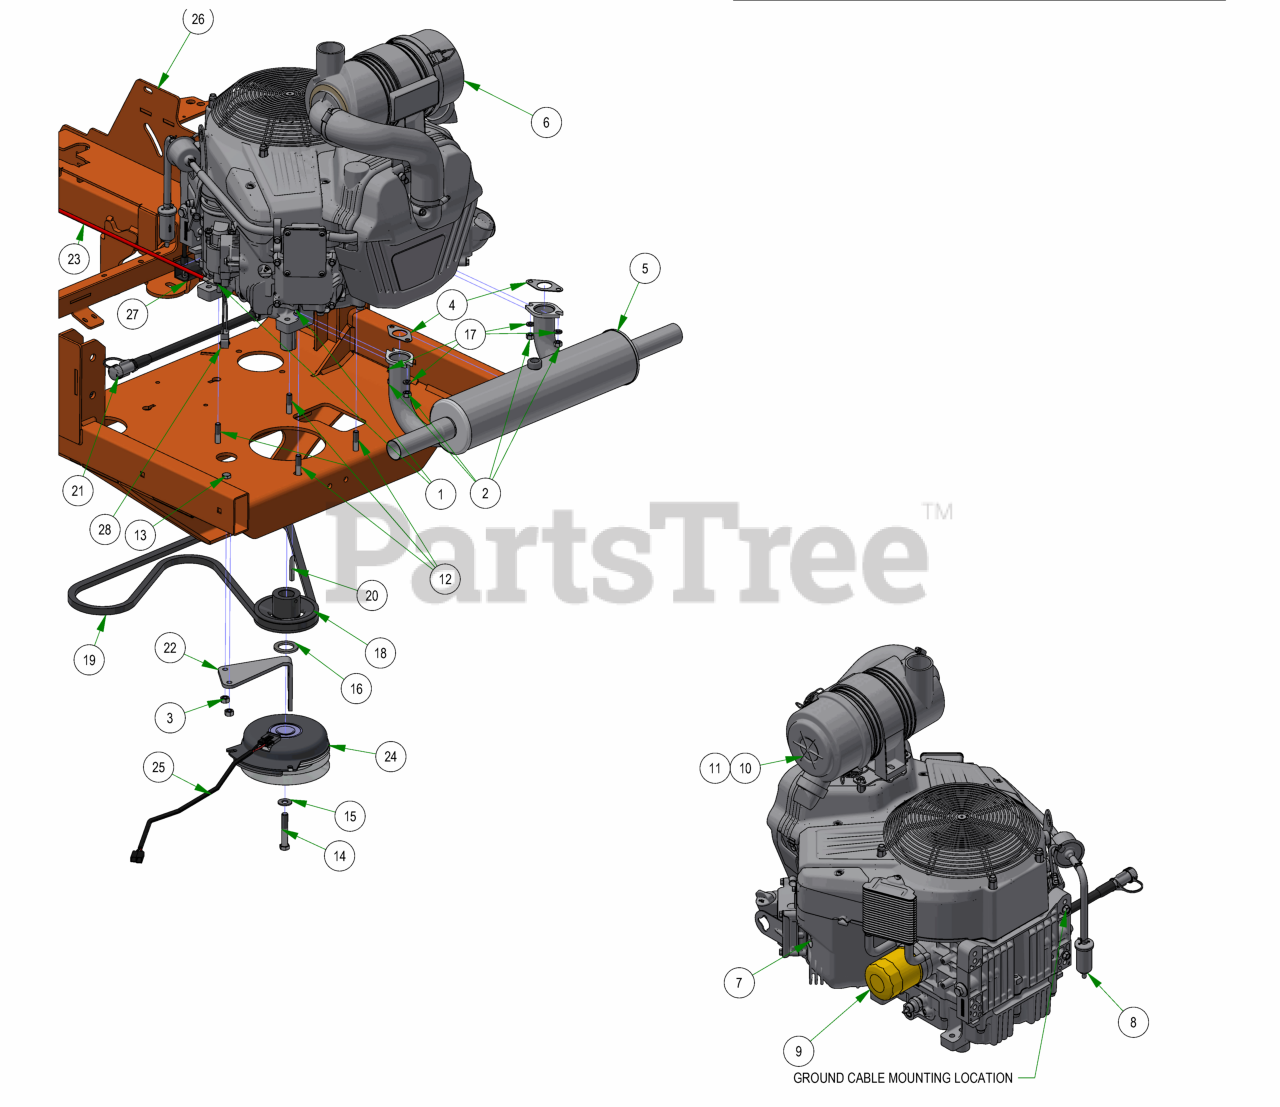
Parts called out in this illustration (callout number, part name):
1	3/8-16 HEX FLANGE TOP LOCKNUT ZINC
2	M8-1.25 DIN 934 HEX NUT (CL.8) ZINC
3	3/8-16 HEX NUT ZINC
4	Exhaust Gasket for 23 Vanguard
5	Muffler for 36Hp Vanguard
6	Vanguard 37 EFI Vertical Shaft Electric Throttle
7	Spark Plug
8	Universal Inline Fuel Filter
9	Oil Filter
10	Canister Air Filter- Outer
11	Canister Air Filter- Inner
12	3/8-16x1-3/4 Gr5 Hex Flange Screw Zinc Clear
13	3/8-16 X 1-1/4 HEX CAP SCREW (GR.5) ZINC
14	7/16-20 X 2-1/2 HEX Bolt GR 8 W/ Patch
15	3/8 FLAT WASHER USS (1" OD) ZINC
16	1.140 ID X 1.750 OD X .132 THICK FLAT WASHER PLAIN
17	5/16 SPLIT LOCKWASHER ZINC
18	4 3/4 Motor Pulley
19	2019 Rogue Pump Belt 68"
20	1/4 X 2 SQ MACHINERY KEY 1018 STL PLAIN
21	14mm Oid Drain - 36hp Vanguard
22	PTO Engager Holder
23	24" Red Battery Cable
24	Clutch Assembly
25	Clutch Pigtail
26	2023 Rogue Frame - Painted
27	Starter Cable
28	2019 Harness Adaptor - Vanguard 37 EFI Vert/Horiz
